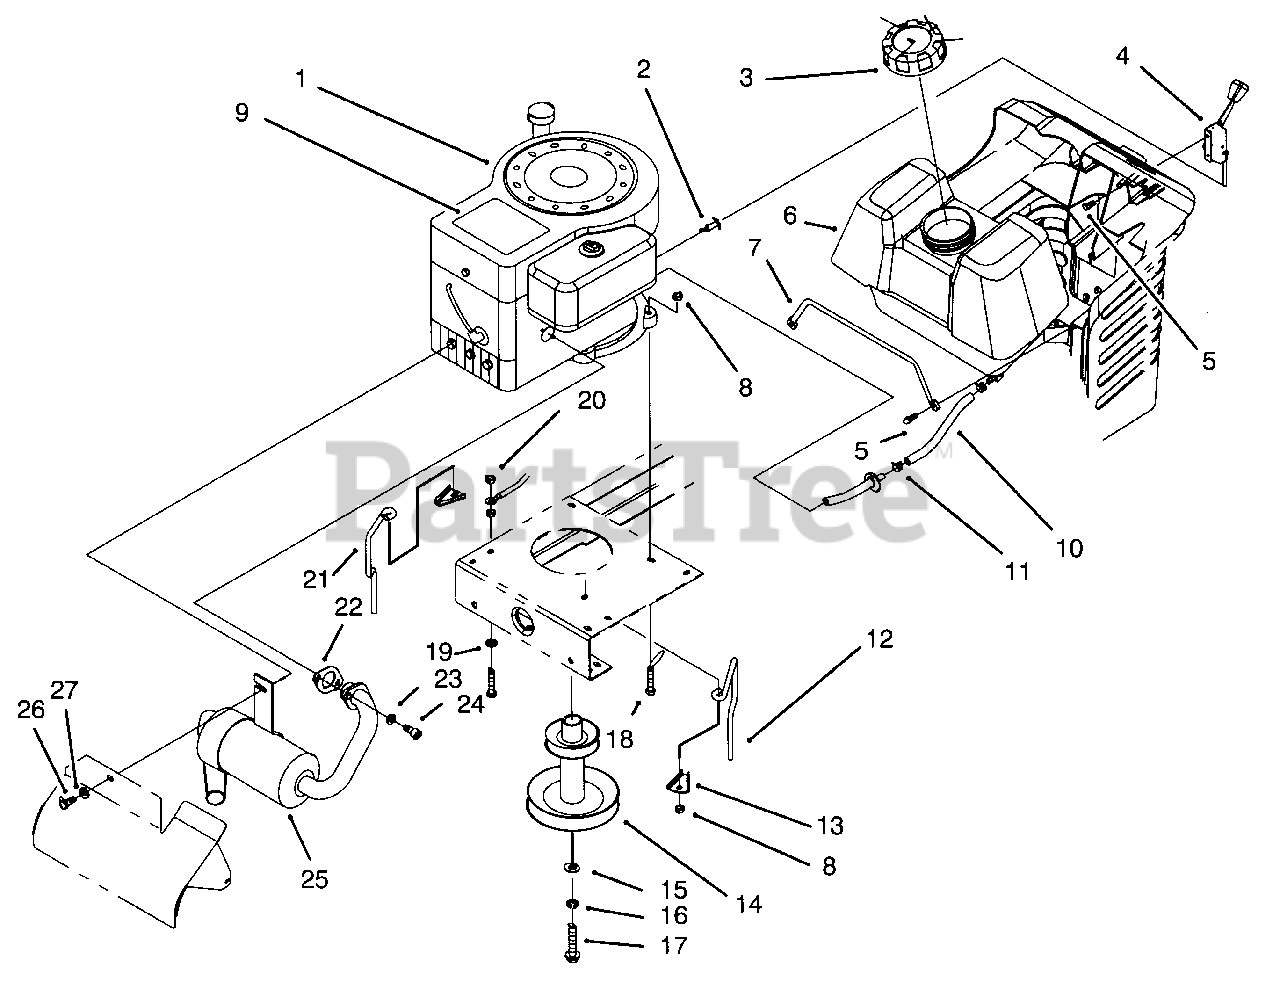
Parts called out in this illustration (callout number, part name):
1	Engine-12.5 H.P
2	Cable-Throttle
4	Control-Throttle
5	Screw-Plastite
6	Tank-Gas
7	Rod-Gas Tank
8	Nut-Lock
9	Decal-Engine 12.5
10	Line-Fuel
11	Clamp-Hose
12	Guide-Belt L.H.
13	Anchor-Belt Guide
14	Pulley-Engine
15	Washer-Flat
16	Washer-Lock
17	Bolt-Blade
18	Screw-Hex Hd. Cap
19	Washer-Ext. Tooth Lock
20	Nut-Keps
21	Guide-Belt R.H.
22	Gasket-Muffler
23	Washer-Lock
24	Screw-Hex Soc. Hd.
26	Screw-Hex Hd. Cap
27	Washer-Lock
